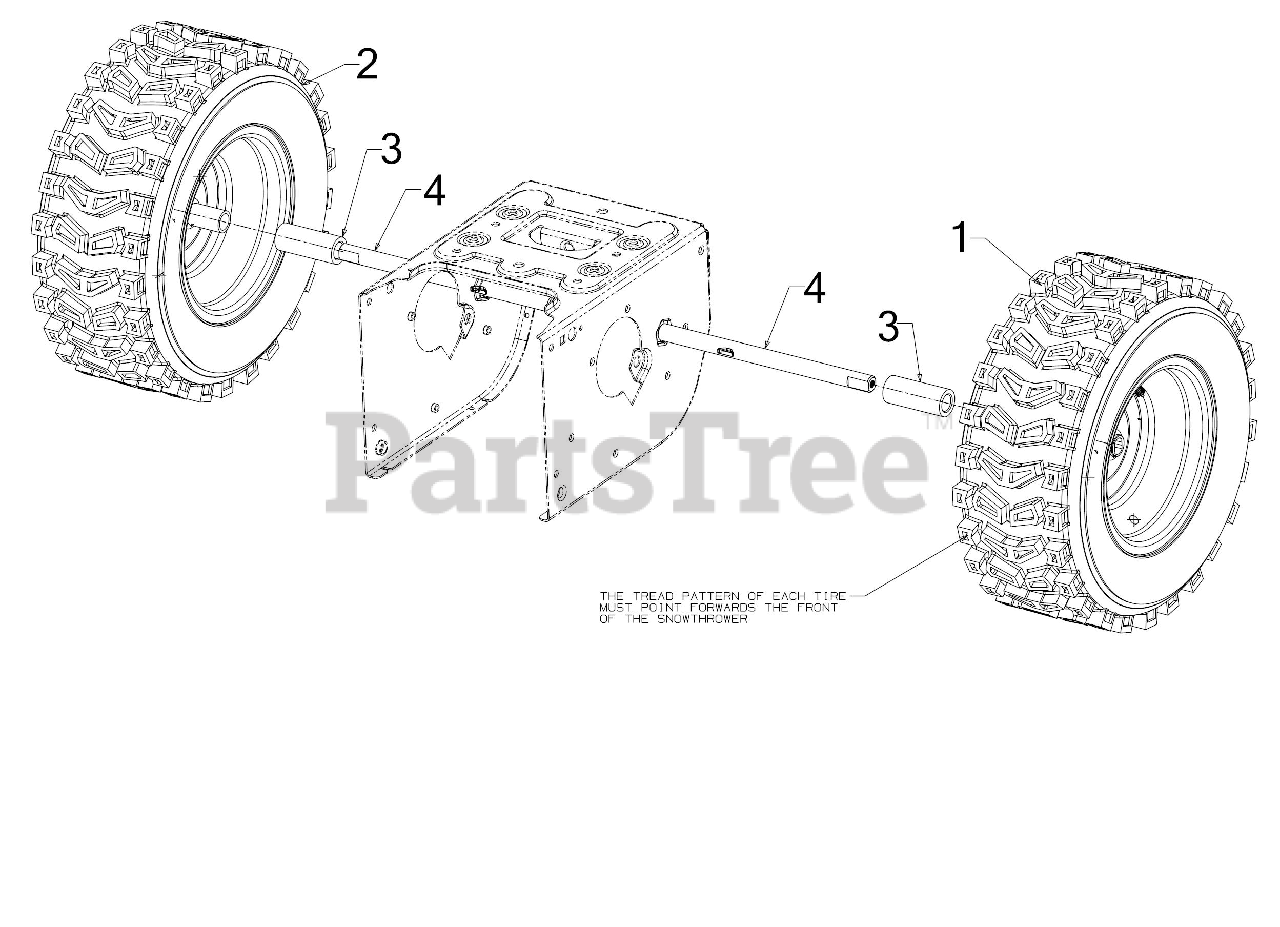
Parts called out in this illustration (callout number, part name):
1	WHEEL ASSEMBLY (16 x 6.5 x 8) (LH)
2	WHEEL ASSEMBLY (16 x 6.5 x 8) (RH)
3	WHEEL SPACER 1.25ODX.75X3.00
4	AXLE .75OD x 11.12LG
